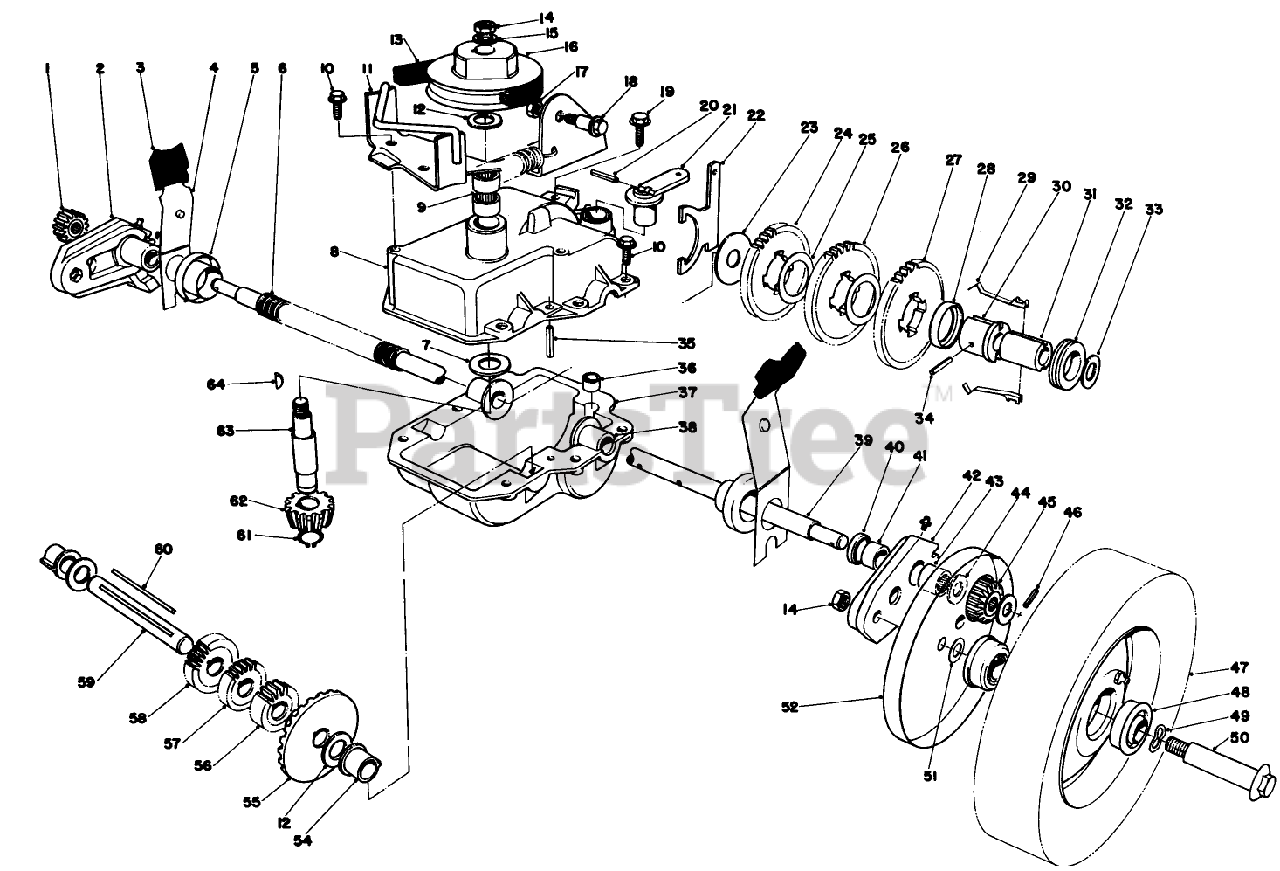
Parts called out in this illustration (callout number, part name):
1	RH CLUTCH & PINION
3	KNOB-ARM
5	End Cap
6	CONDUIT-CONVOLUTED, SPLIT
12	WASHER-THRUST
13	V-BELT
15	WASHER-FLAT
16	PULLEY
19	SCREW-THD ROLL, HWH
20	PIN-SPRING
21	LEVER-SHIFT
23	WASHER
25	WASHER
29	KEY-SHIFT
31	SLEEVE
32	COLLAR-SHIFT
33	WASHER-PLAIN
35	ROLL PIN 3/16 X 1 IN
36	BUSHING-YOKE
39	OUTPUT SHAFT
41	Bushing
44	WASHER
45	LH CLUTCH & PINION
48	BEARING-BALL
49	SPRING WASHER
50	Wheel Bolt
51	WASHER
56	14 T GEAR
58	GEAR-18T
61	RING-RETAINING
62	PINION-BEVEL
64	KEY-WOODRUFF
